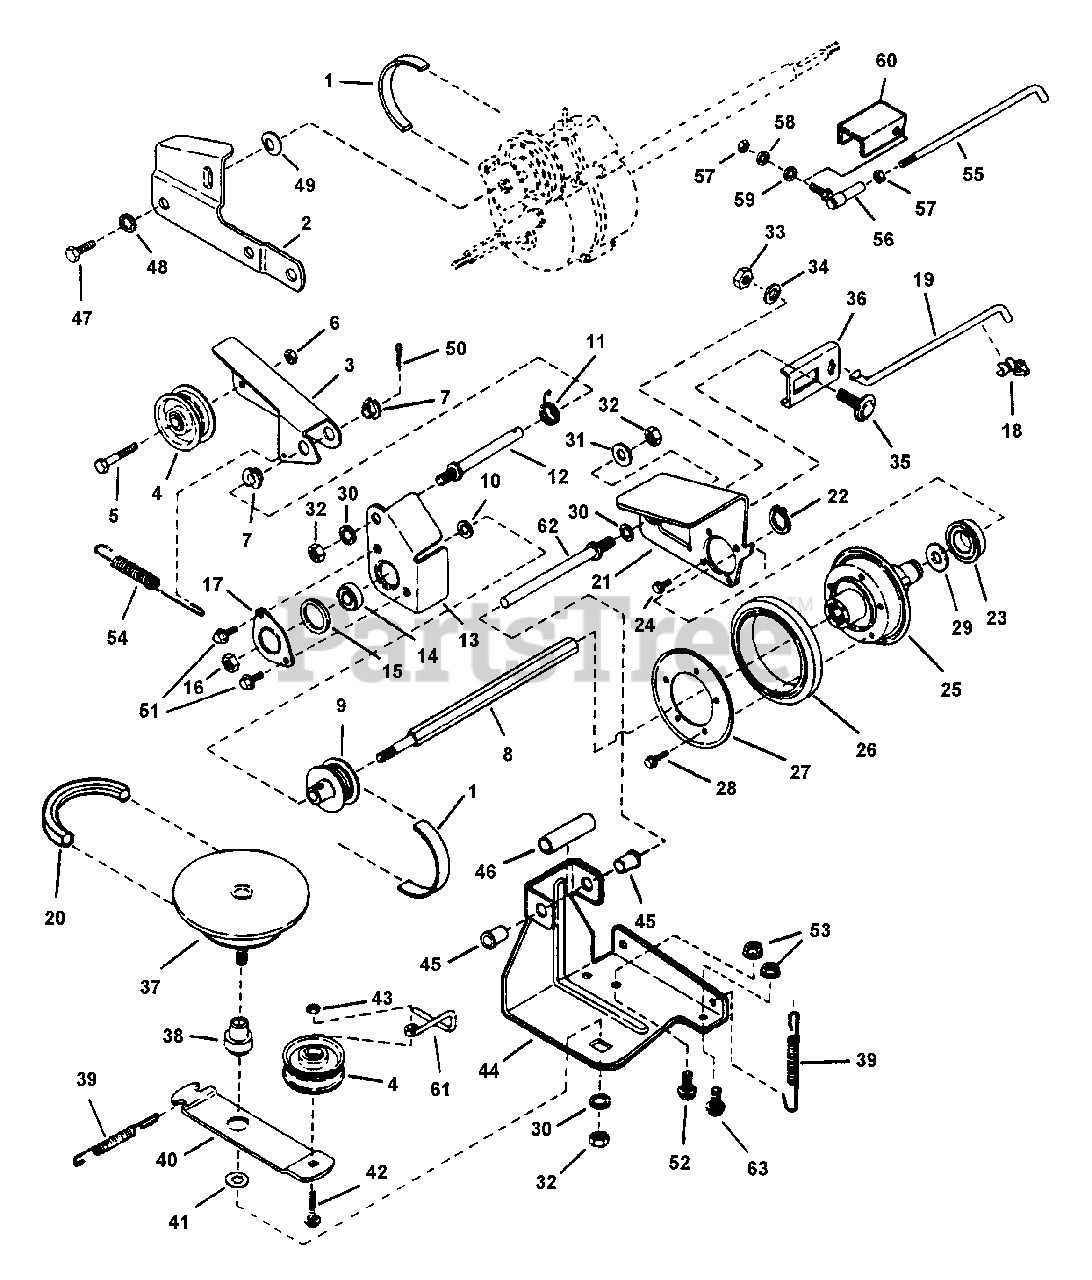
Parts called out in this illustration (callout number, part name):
1	BELT, Poly-Vee
2	LINK, Differential
3	ARM, Clutch Idler
4	PULLEY, Idler
5	SCREW, 1/4-28 x 1-3/8" Hex Head Cap, Grade 5
6	NUT, 1/4-28 Hex Top Lock
7	BUSHING, 3/8 I.D. Nylon
8	SHAFT, Hex Drive
9	PULLEY, Poly-V (2" O.D.)
10	WASHER, 3/8" Flat
11	SPRING, Torsion
12	STUD
13	HOLDER, Bearing (Inner Half)
14	BEARING, Ball
15	O-RING
16	NUT, 3/8-24 Hex Center Lock, Grade 5
17	HOLDER, Bearing (Outer Half)
18	CLIP, 1/4 Right Arc (Transfer Rod)
19	ROD, Transfer (Except European)
20	BELT, Engine Drive
21	PLATE, Thrust
22	RING, Retaining
23	BEARING, Ball
24	SCREW, #10-32x1/4" Self-Tapping Machine
25	ASSEMBLY, Hub (Includes 11108 Bushing & 90913 Screws)
26	RING, Driven
27	PLATE, Ring Retaining
28	SCREW, #10-24 x 1/2" Self-Tapping Machine (Torx)
29	WASHER, 3/4 Shim
30	WASHER, 3/8 Internal Tooth Lock
31	WASHER, 3/8" Flat
32	NUT, 3/8-24 Hex, Grade B
33	NUT, 5/16-18 Hex, Grade 5
34	WASHER, 5/16 Split Lock
35	BOLT, 5/16-18 x 3/4" Carriage, Grade 5
36	CONNECTOR, Transfer Rod
37	KIT, Drive Disc Assembly
38	BUSHING
39	SPRING (Wheel Drive & Idler)
40	ARM, Idler
41	RETAINER, 3/8" Bolt
42	BOLT, 1/4-20 x 1-1/2" Carriage, Grade 5
43	NUT, 1/4-20 Hex Center Lock, Grade 5 or B
44	BRACKET, Deck
45	BUSHING, Flange
46	SPACER
47	SCREW, 5/16-18 x 1/2" Hex Head Cap, Grade 5
48	WASHER, 5/16 Internal Tooth Lock
49	WASHER, Spring
50	PIN, 3/32 x 1/2" Cotter
51	SCREW, 1/4-20 x 1/2" Self-Tapping
52	BOLT, 5/16-18 x 1/2" Short Neck Carriage, Grade 5
53	NUT, 5/16-18 Hex Flange Lock, Grade 5
54	SPRING, Clutch
55	LINK, Transfer
56	JOINT, Ball
57	NUT, 1/4-28 Hex, Grade 5
58	WASHER, 1/4 Flat
59	WASHER, 1/4 Internal Tooth Lock
60	SHIELD, Hex Shaft
61	SCRAPER, Drive Pulley
62	GUIDE, Thrust Plate
63	BOLT, 5/16-18 X 5/8" Short Neck Carriage, Grade 5
